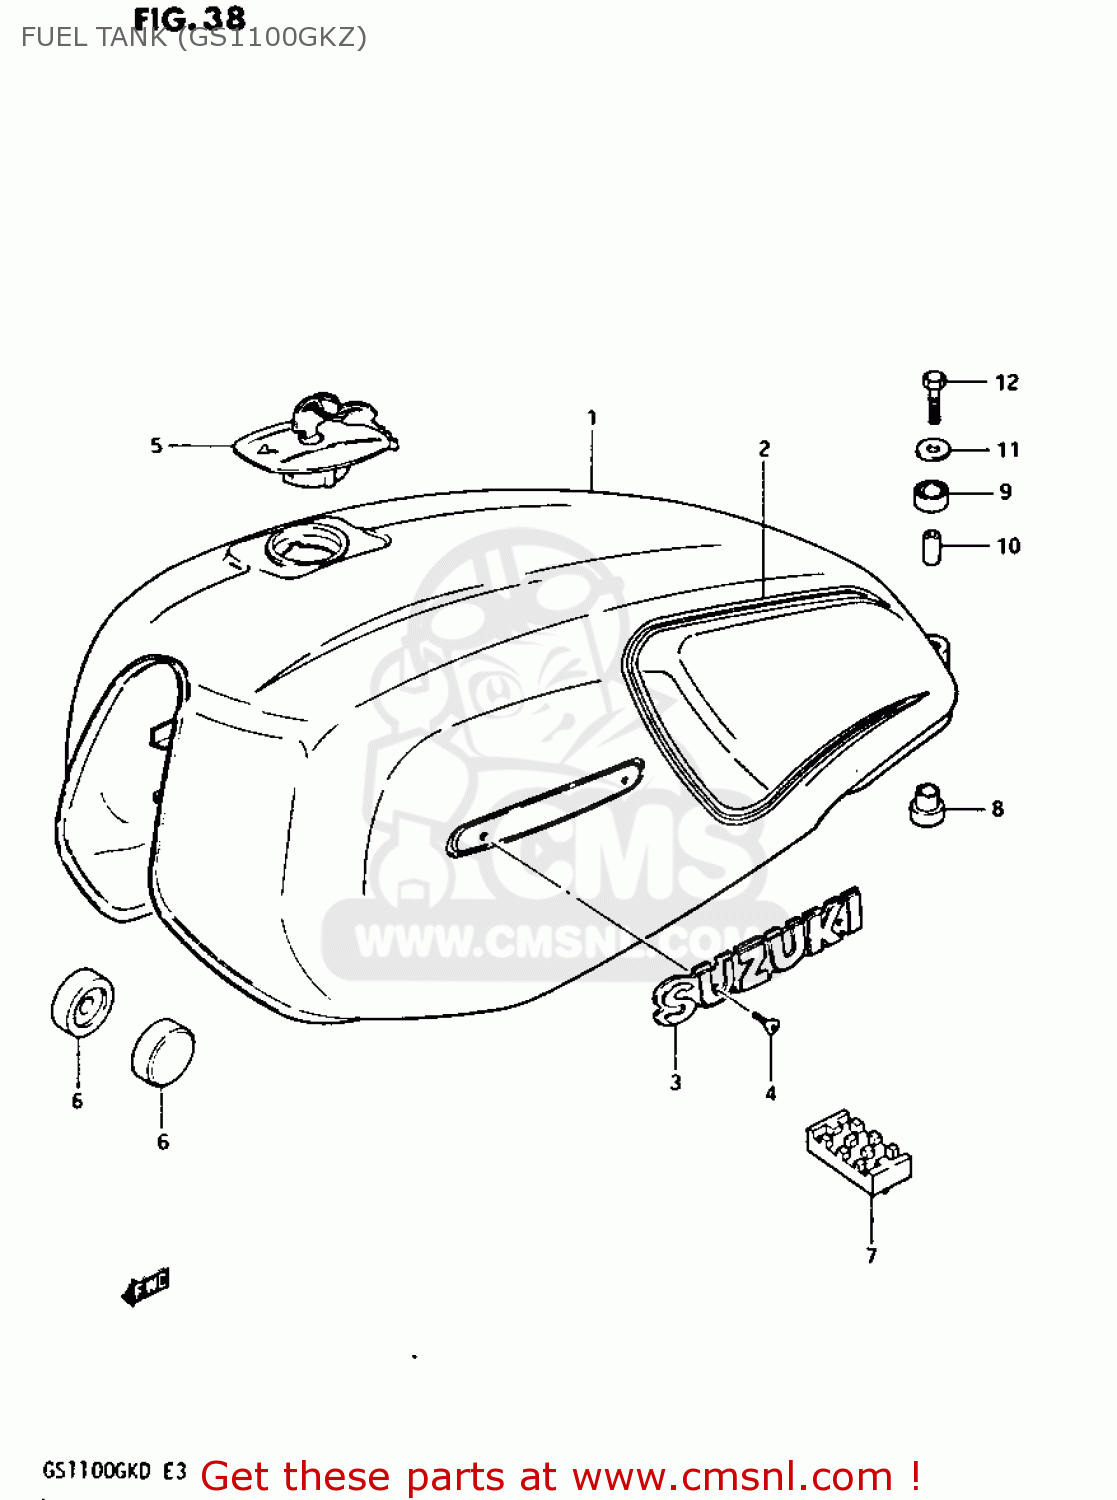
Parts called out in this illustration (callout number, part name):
1	TANK ASSEMBLY,FUEL
2	TAPE SET,FUEL TANK
3	EMBLEM
4	SCREW 3X6
5	CAP SET,FUEL TANK
6	CUSHION
7	CUSHION,FUEL TANK
8	CUSHION
9	CUSHION
10	SPACER (6.4X9X21.5)
11	WASHER (6.5X24X1.6)
12	BOLT
